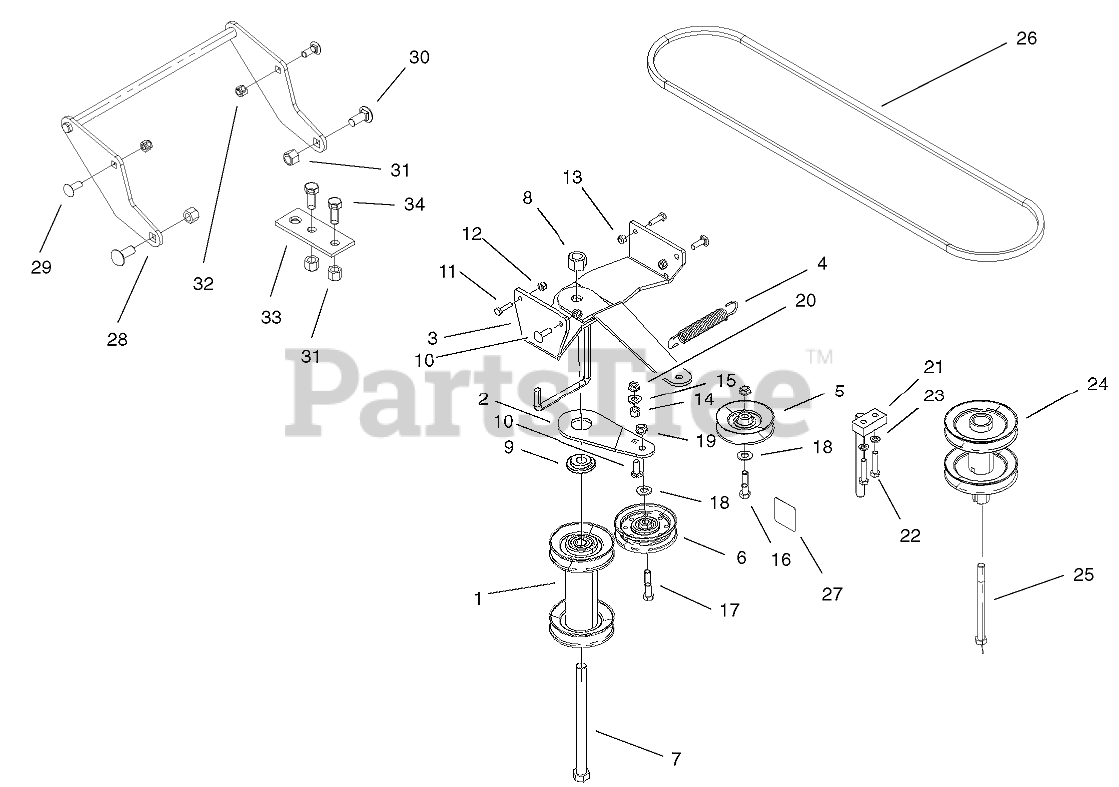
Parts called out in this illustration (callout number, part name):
1	Pulley-Double
2	Arm-Idler
3	Frame-Drive
4	SPRING
5	Pulley-V
6	IDLER-FLAT
7	Screw-HH
8	NUT-LOCK, NI
9	Washer-Flange
10	SCREW-CARR
11	SCREW-HH
12	NUT-LOCK, NI
13	NUT-LOCK, NI
14	Sleeve
15	WASHER-FLAT
16	SCREW-HH
17	SCREW-HH
18	WASHER-FLAT
19	NUT-HHF, WHIZ
20	NUT-HF
22	SCREW-HH
23	WASHER-LOCK
24	Pulley-Engine
25	SCREW-HH
26	Belt-V
27	DECAL-HAZARD, PINCHED FINGER
28	Hitch-Quick, Tractor
29	BOLT-CARR
30	SCREW-CARR
31	NUT-LOCK, NI
32	NUT-LOCK, NI
33	Plate-Hitch
34	SCREW-HH
